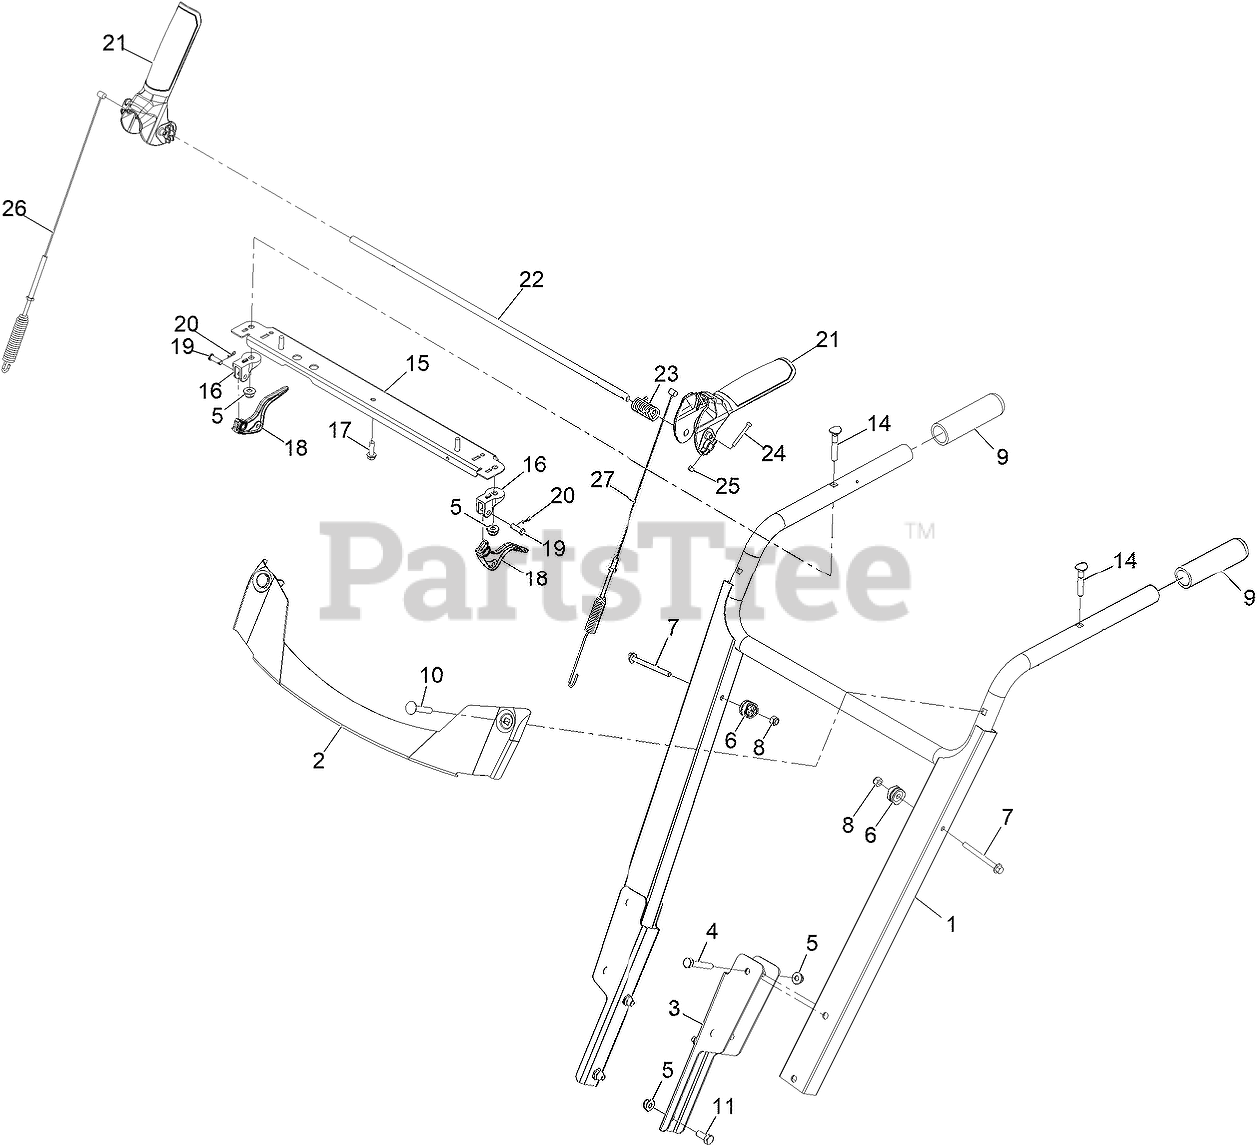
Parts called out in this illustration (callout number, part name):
1	HANDLE ASM HD, WELDED
2	METAL TRIM, HD
3	BRACKET-HANDLE, LOWER
4	SCREW-HH
6	CLAMP-CABLE
7	SCREW-HHF
8	NUT-HEX
9	GRIP-HANDLE
10	BOLT-CARR
11	SCREW-HH
14	SCREW-HANDLE
15	BRACE-CONSOLE
16	MOUNT-LEVER, CLUTCH
17	SCREW-PLASTITE, HWH
18	LEVER-CLUTCH
19	PIN-CLEVIS
20	PIN-HAIR
21	LEVER-CONTROL
22	ROD-LOCKOUT
23	SPRING-TORSION, HANDLE RETURN
24	SCREW-HSH M4-0.7 X 36MM
25	NUT-HEX NYL INS M4-0.7
26	CABLE-AUGER
27	CABLE-TRACTION
